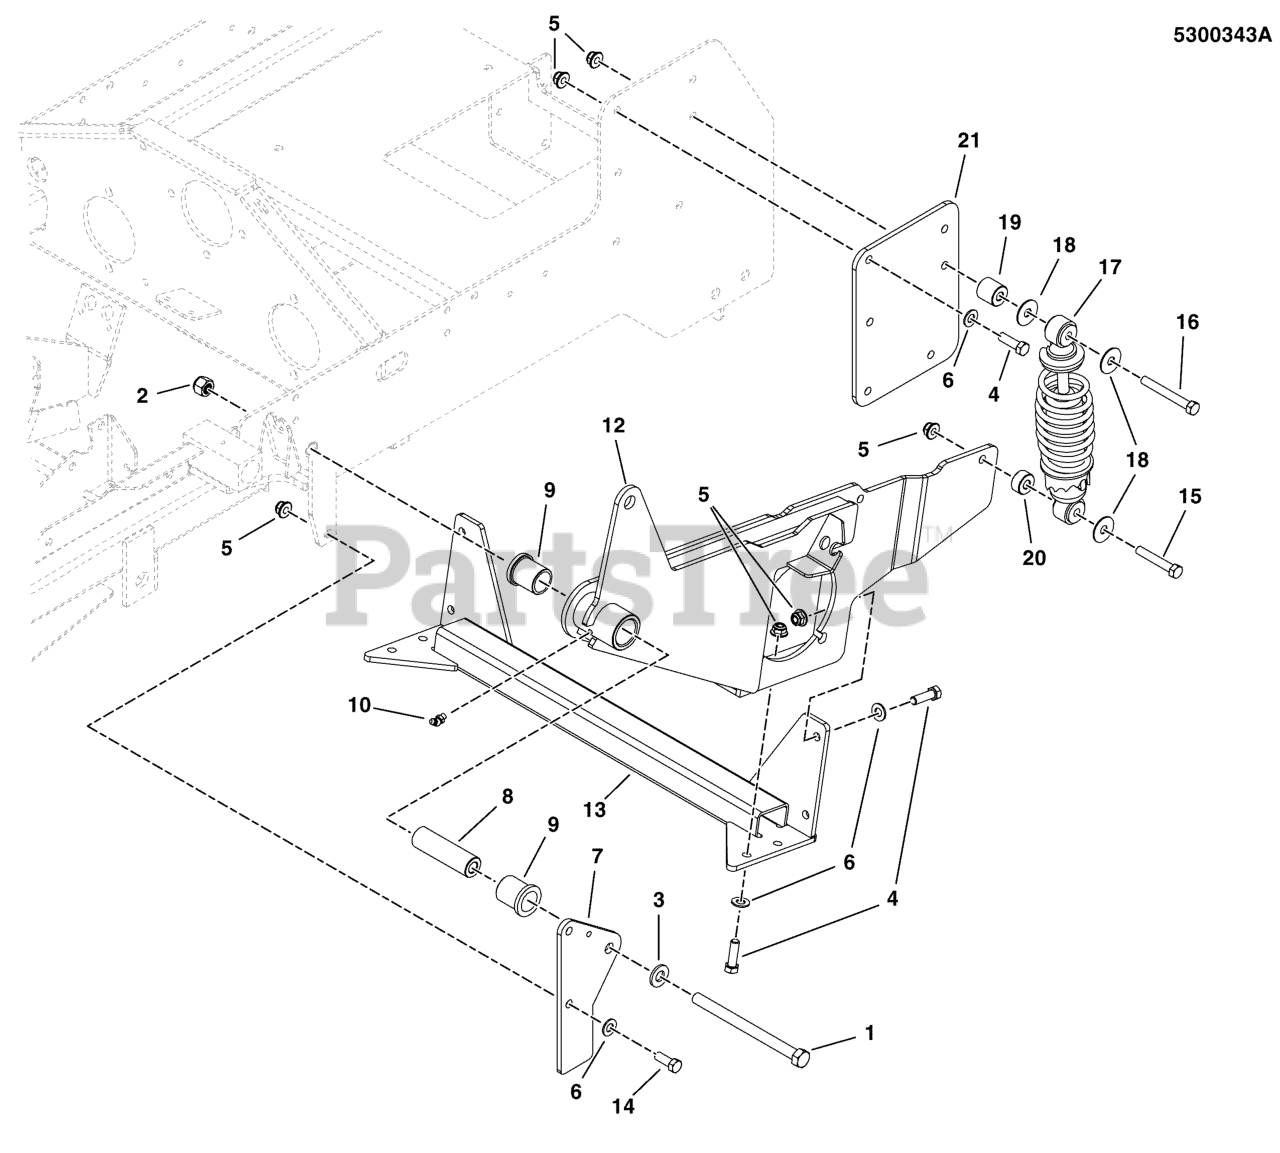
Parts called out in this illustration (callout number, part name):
1	BOLT, 1/2-13 X 6-1/2 GD8, YZ
2	NUT, 1/2-13 HEX NYLON LOCK
3	WASHER, 1/2 GD9 YZ
4	BOLT, 3/8-16 X 1-1/4" GD5 CZ
5	NUT, 3/8-16 HEX NYLOCK FLANGE
6	WASHER, 3/8 GD.9 FLAT
7	SUPPORT, SWING ARM - BLK
8	SPACER, .52 X 1.00 X 3.42
9	BUSHING, FLANGE
10	GREASE FITTING, 45 DEGREE
14	BOLT, 3/8-16 X 1" GD5 CZ
15	BOLT, 3/8-16 X 2-1/4 GD5 TFL
16	BOLT, 3/8-16 X 3" GD5 CZ
17	COIL-OVER SHOCK ASSEMBLY
18	WASHER-3/8 FENDER
19	SPACER, SHOULDER
20	SPACER, .39 X 1.00 X .50
21	PLATE, FRAME SUPPORT, LH - RED
